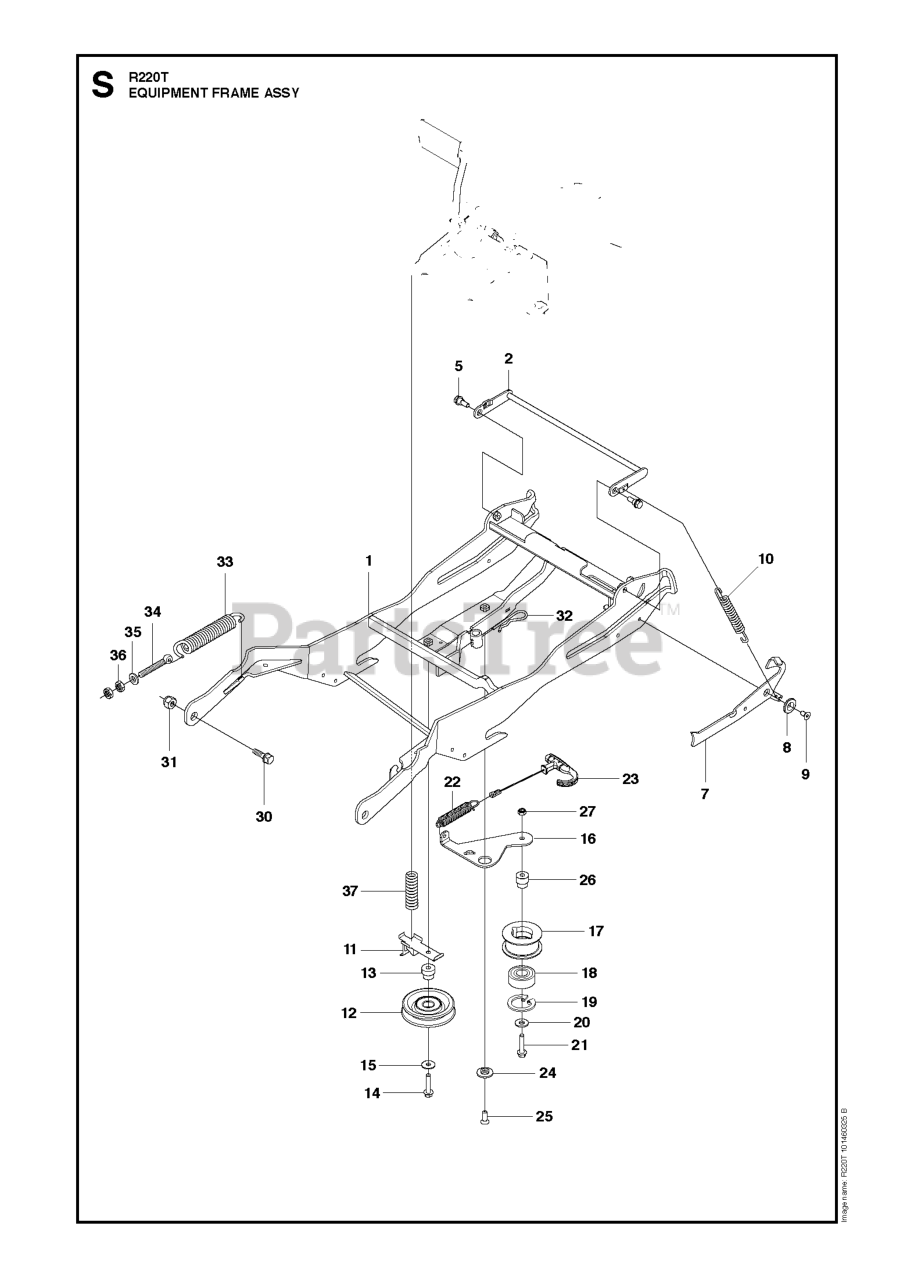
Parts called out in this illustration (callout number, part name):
1	EQUIPMENT FRAME
8	SPACER
9	SCREW IHCSFM
11	BRAKE
17	BELT TENSIONER WHEEL ASSY
18	BALL BEARING 6004-2RS1
19	RETAINING RING
23	HANDLE ASSY
24	WASHER
27	LOCKNUT M8
31	Lock Nut, Fiber M12 DIN 985 Z/P
35	WASHER
36	NUT
